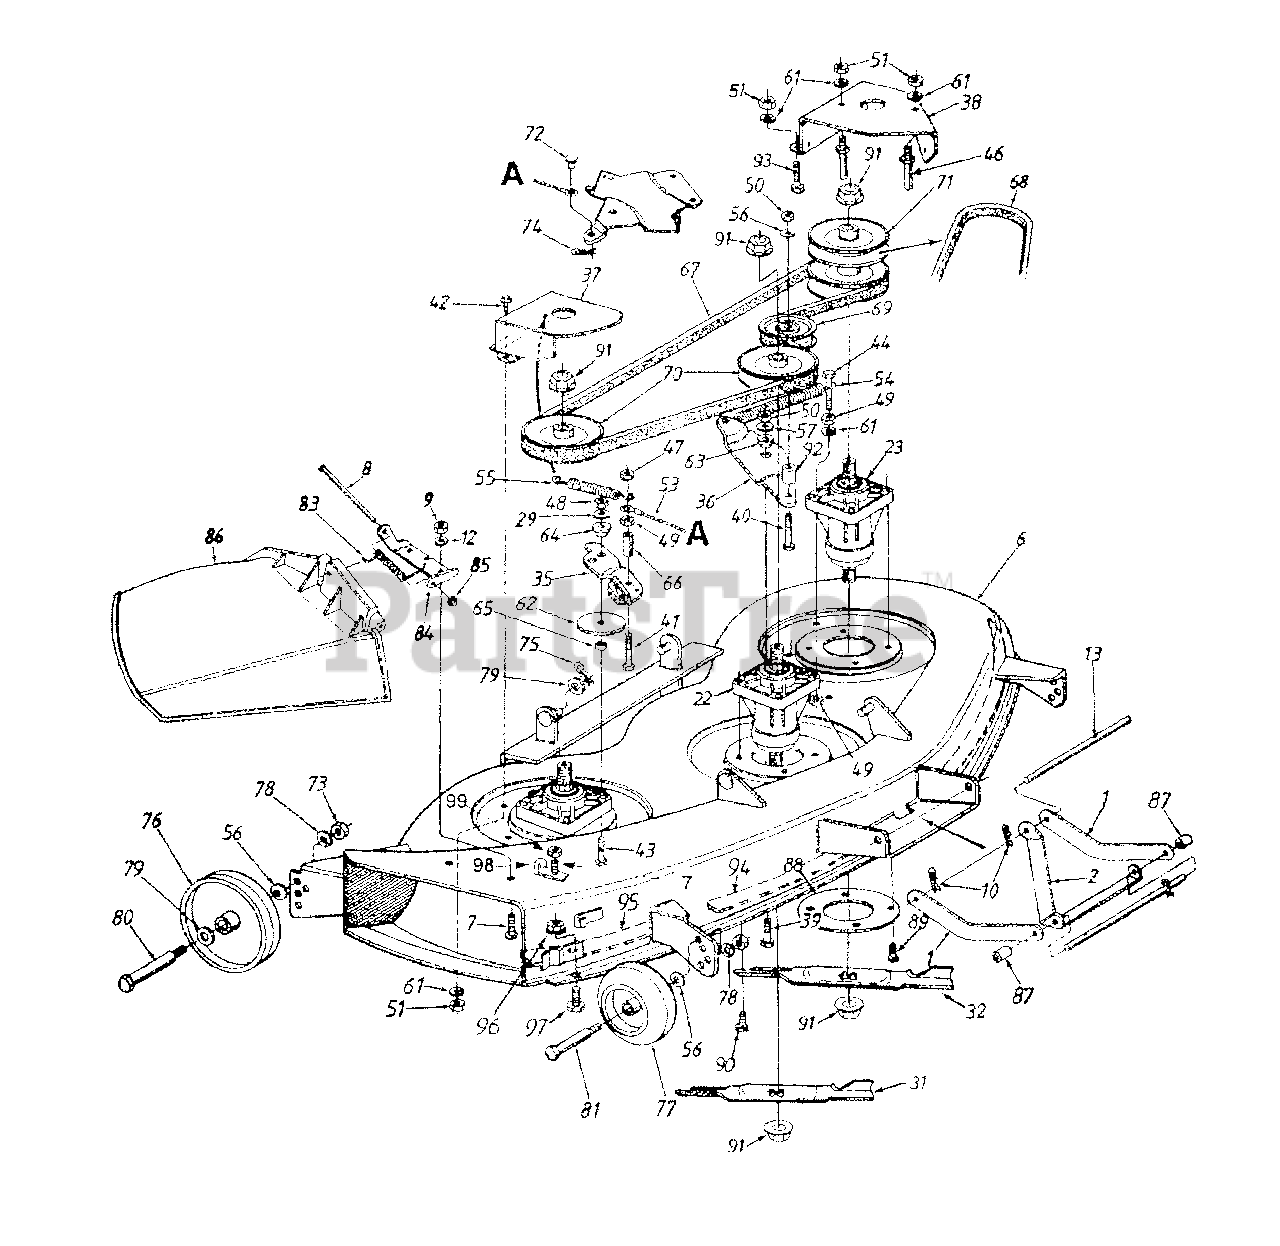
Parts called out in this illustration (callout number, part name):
7	Hex Bolt 1/4-20 x .62"
8	Hinge Pin
9	Hex Nut 1/4-20 Thd.
10	Hairpin Clip
12	Bell-Wash. 1/4" I.D.
13	Deck Connecting Rod
22	Spindle Assembly R.H. & Center
23	Spindle Assembly L.H.
29	Lock Wash. 5/16" I.D.
31	Blade 14.88" Middle
32	Blade 16.28" R.H. & L.H.
35	Deck Brake Brkt. Assembly
36	Idler Bracket
39	Hex Bolt 3/8-24 x 1.0"
40	Hex Bolt 3/8-24 x 2"
41	Hex Bolt 1/4-28 x 1.75"
42	Hex Wash. Hd. Tap-Scr. 1/4-20 x .5"
43	Hex Bolt 5/16-24 x 1.5"
44	Hex Bolt 1/4-28 x 1.5"
46	Belt Guard Pin 1/4" Dia.
47	Hex Cent. L-Nut 1/4-28 Thd.
48	Hex Nut 5/16-24 Thd.
49	Hex Nut 1/4-28 Thd.
50	Hex Nut 3/8-24 Thd.
51	Hex Nut 1/4-20 Thd.
53	Brake Cable Assembly
54	Extension Spring 6.17"
55	Extension Spring 3.97"
56	Bell-Wash. .38" I.D. x .88" O.D.
57	Bell-Wash. .39" I.D. x 1.13" O.D.
61	L-Wash. 1 /4" I.D.
62	Fl-Wash. 5/16" I.D. x 3" O.D.
63	Shld. Spacer.625" I.D.
64	Shld. Spacer
65	Spacer.34" I.D.
66	Spacer.326" I.D.
67	V-Belt
68	V-Belt
69	Fl-Idler Pulley 3.5" O.D.
70	Pulley 5.0" Dia.
71	Double Pulley 5.0" Dia.
72	Clevis Pin 1/4" Dia. x .53"
73	Hex Nut 3/8-16 Thd.
74	Intern. Cotter Pin 5/16" Dia.
75	Intern. Cotter Pin 3/8 Dia.
76	Deck Wheel 5" Dia.
77	Deck Wheel w/Insert 5" Dia.
78	L-Wash. 3/8" I.D.
79	Fl-Wash. .531" I.D.
80	Shoulder Bolt.498" Dia. x 1.64"
81	Shoulder Bolt
83	Torsion Spring
84	Hinge Mtg. Brkt.
85	Push Nut
86	Chute Assembly Comp.
87	Spacer 5/8" I.D. x 7/8" O.D.
90	Hex Wash. Hd. Scr. 5/16-18 x .75"
91	Hex Flange Nut 5/8-18 Thd.
92	Spacer.38" I.D.
93	Hex Bolt 1/4-20 x .5"
96	Hex Sems Nut 1/4-20 Thd.
97	Carriage Bolt 1/4-20 x .5"
98	Retainer Hook Bracket
99	Hex Lock Nut 114-20
